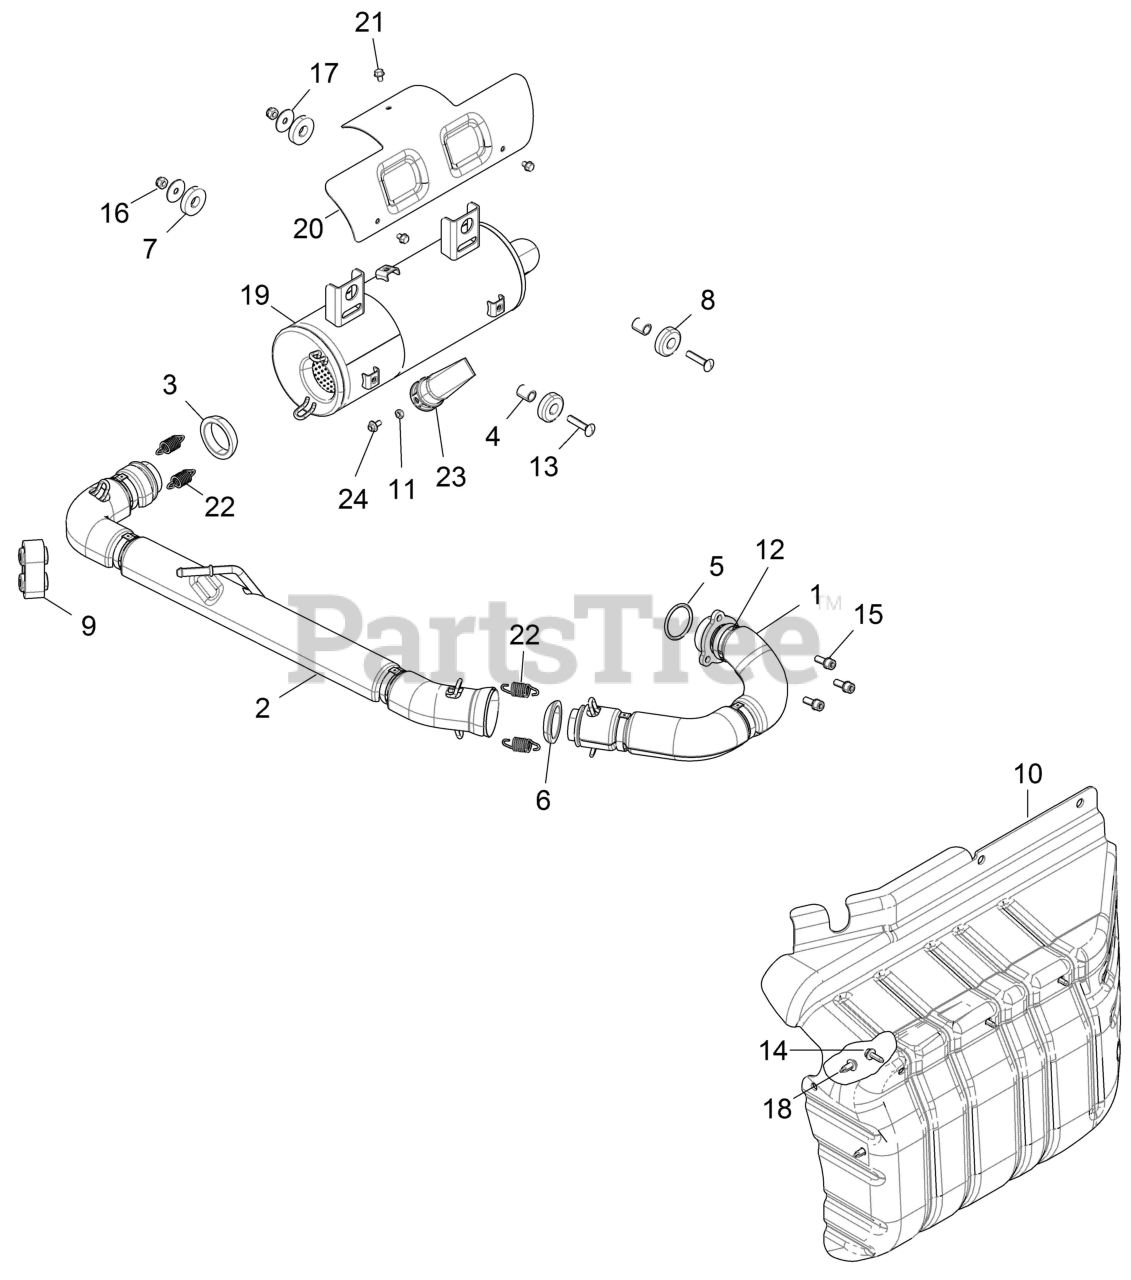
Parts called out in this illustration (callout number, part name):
1	ASM., HEADPIPE, FRONT
1	ASM-HEADPIPE,FRONT,SS
2	ASM., HEADPIPE
3	SEAL-EXHAUST, SOCKET
5	GASKET-EXHAUST SEALING
6	SEAL-EXHAUST
7	WASHER, SILENCER MOUNT
8	DAMPER-VIBRATION
9	MOUNT-ISOLATOR
10	SHIELD, HEAT, FOIL, FULL, RGR
12	CLAMP, HEAT SHIELD, EXHAUST
13	SCR-CAR M8X1.25 40 8.8 ZOD
14	SCR-M6X1.0X20,HXHD,FLG,TDFM,BL
15	SCR-M8X1.25X22,HX/SO
16	NUT-M8X1.25,FLG,NYLOC-OLIVE D
18	RIVET-TUFLOK,.315-.325X.787 (5
19	ASM., SILENCER
20	SHIELD-SILENCER
21	SCREW(10)
23	ARRESTOR, SPARK
24	SCREW,HXFLGHD,M6X12
